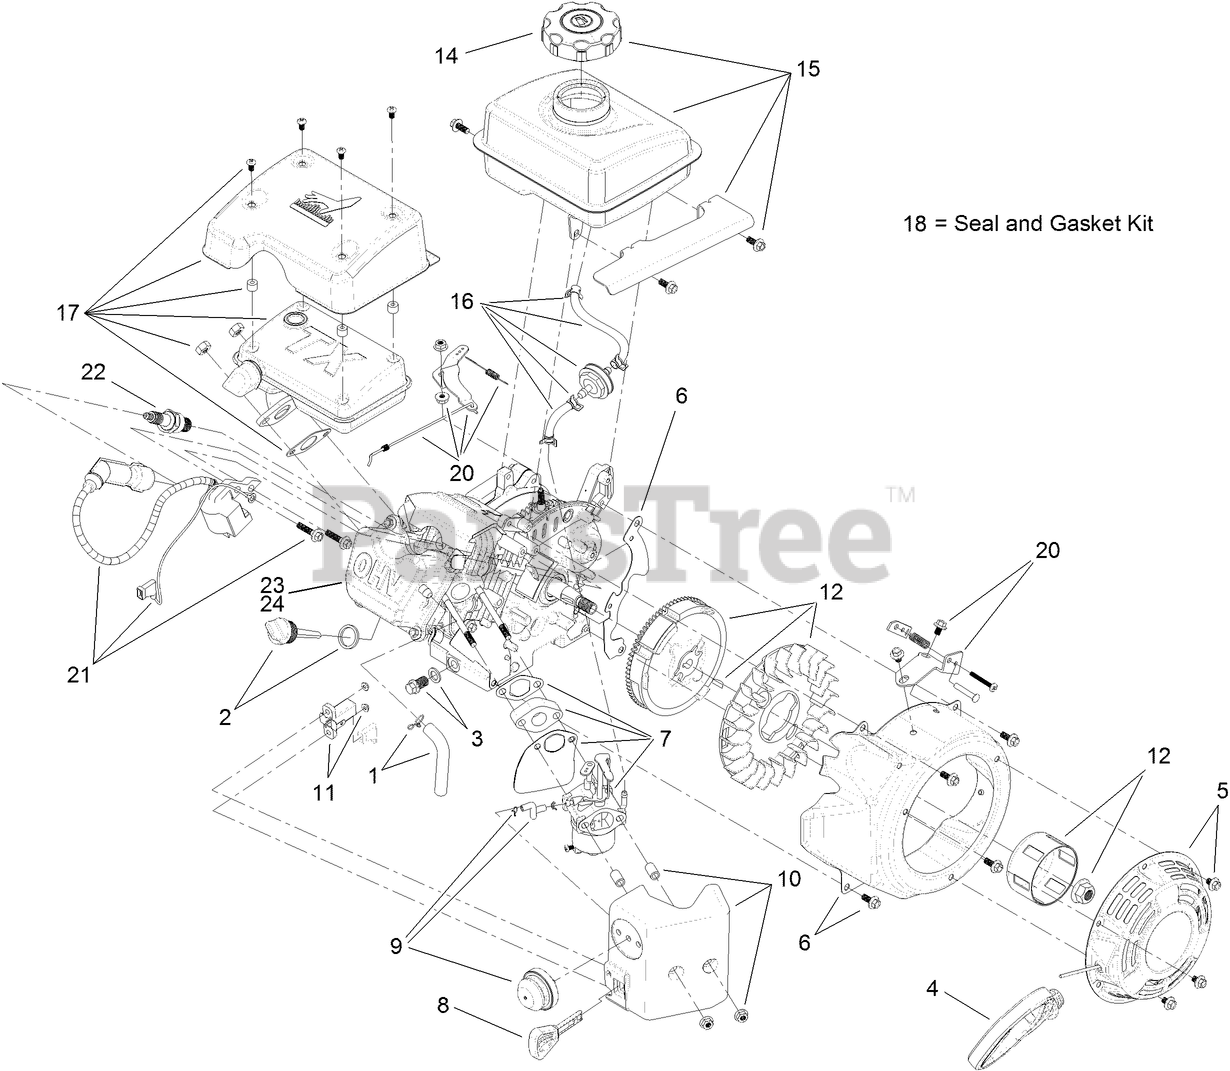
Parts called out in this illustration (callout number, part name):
1	BREATHER TUBE KIT
2	DIPSTICK AND O-RING KIT
3	DRAIN PLUG KIT
4	MITTEN GRIP KIT
5	RECOIL ASM KIT
6	BLOWER SHROUD KIT
7	COMPLETE CARB SERVICE KIT
8	KEY AND LANYARD KIT
9	PRIMER BULB KIT
10	HEATER BOX KIT
11	SWITCH KIT
12	FLYWHEEL AND FAN KIT
22	SPARK PLUG
23	GASKET-COVER, VALVE
24	VALVE COVER ASM
